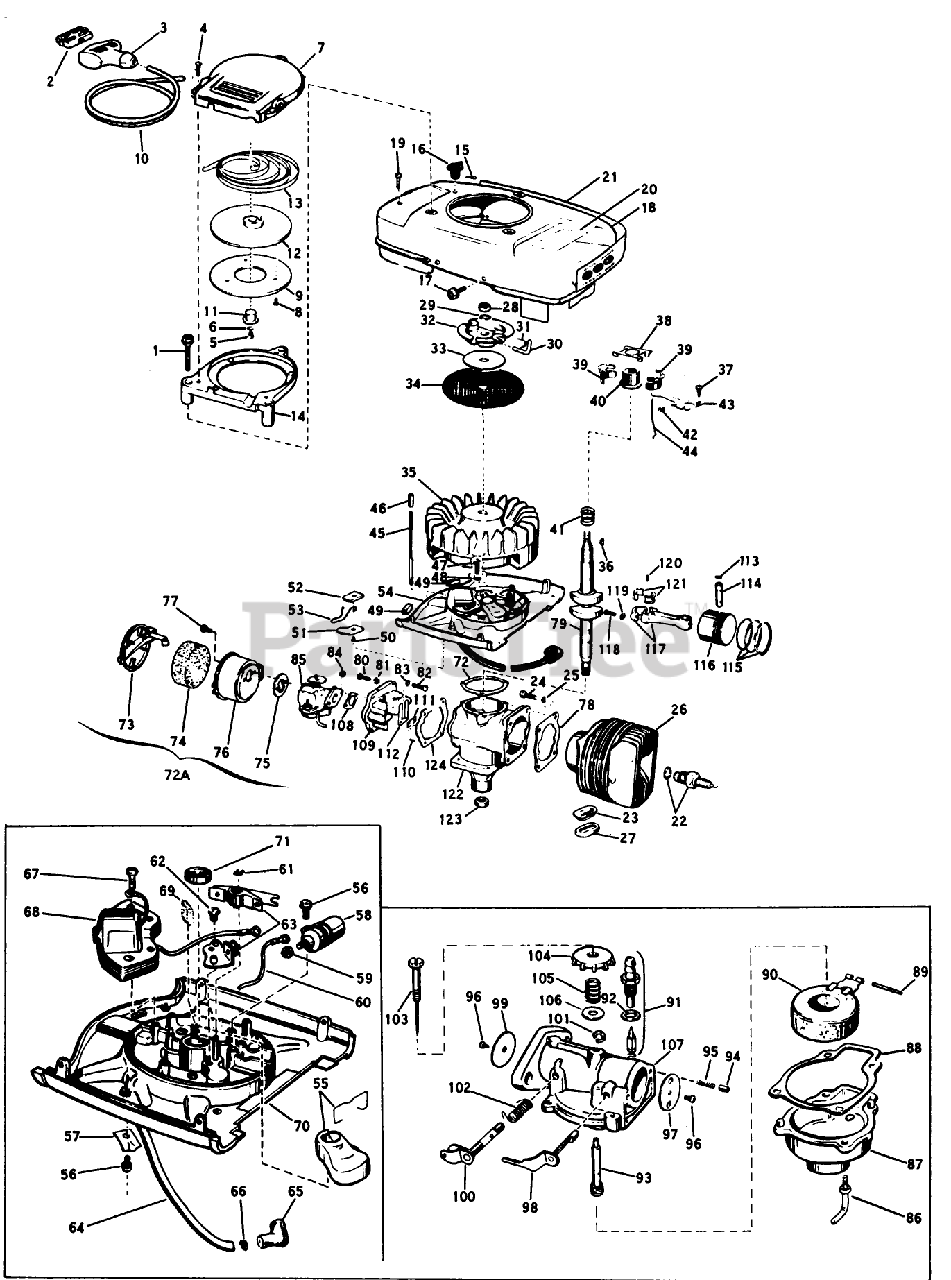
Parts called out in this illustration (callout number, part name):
9	Plate-Pulley
13	RECOIL SPRING
15	Cotter Pin
16	KNOB, CHOKE BAR
17	SCREW S
21	Decal-"Lawn-Boy"
22	Spark Plug Gasket
27	GASKET S
30	PIN - STARTER
40	COLLAR S
42	WEAR BLOCK S
43	GOVERNER LEVER AY
44	GOVERNOR ROD S
50	Screw Shut-off Switch
63	BREAKER AY. S
65	Cover-Rubber
72	GASKET S
74	AIR FIL.ELEM S
77	SCREW S
78	GASKET S
80	SCREW S
84	STOP NUT
96	Screw-Choke Disc
98	CHOKE SHAFT&LVR AY
103	NEEDLE AY. S
105	Spring-Ndl. Adj.
108	GASKET S
111	PLATE-BACKUP, REED
113	RING-RETAINING
121	LINER ASM
